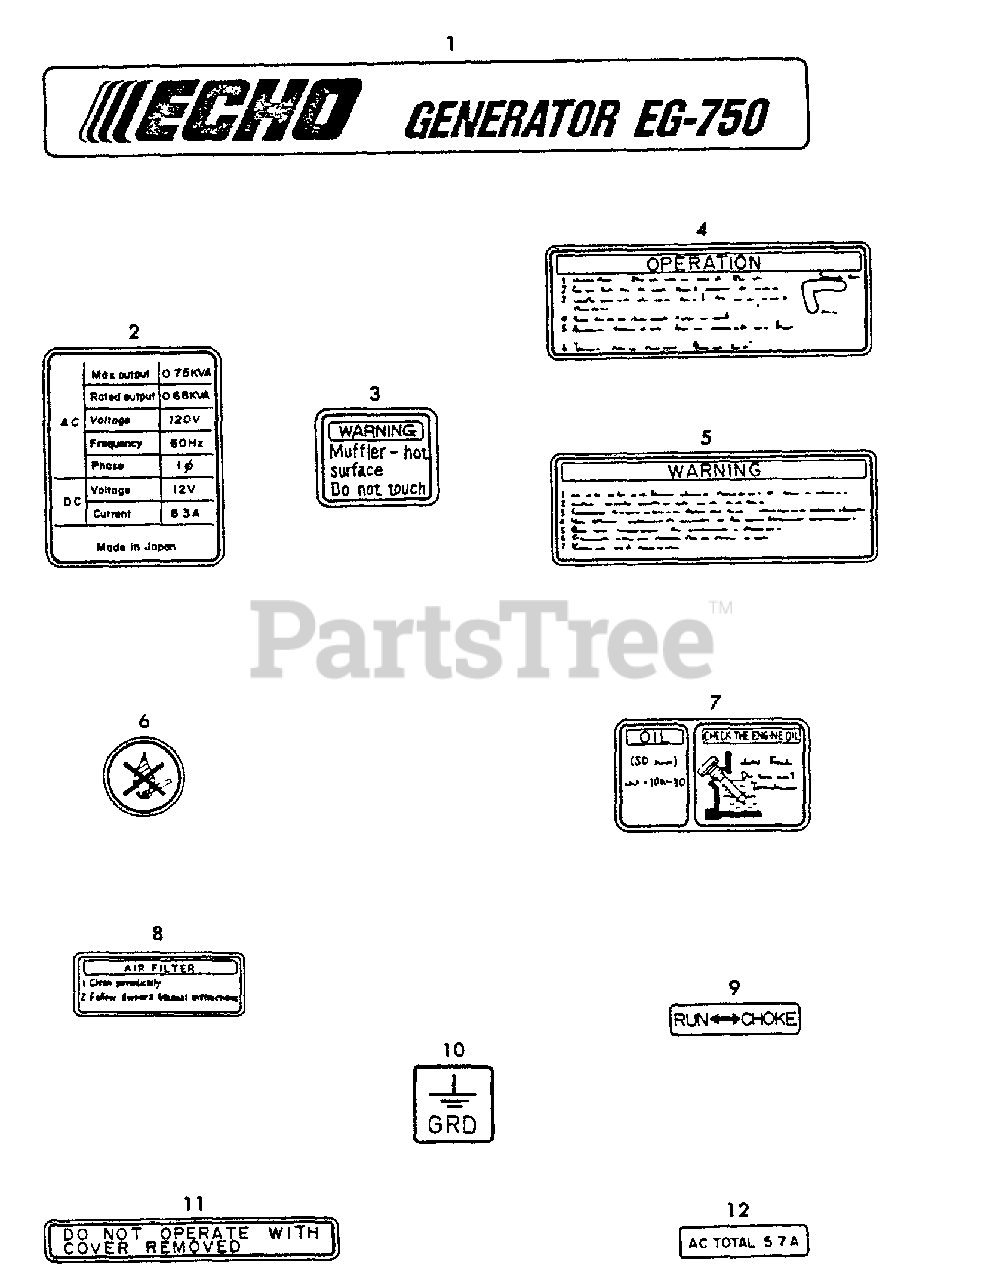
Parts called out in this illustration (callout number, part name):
1	LABEL - MODEL EG750
2	LABEL - GENERATOR
3	LABEL - CAUTION
4	LABEL - CAUTION -- OPERATION
5	LABEL - WARNING
6	LABEL, NON FIRE
7	LABEL, OIL
8	LABEL - AIR FILTER
9	LABEL - CHOKE
10	LABEL, EARTH
11	LABEL - CAUTION
12	LABEL, AMPERE
